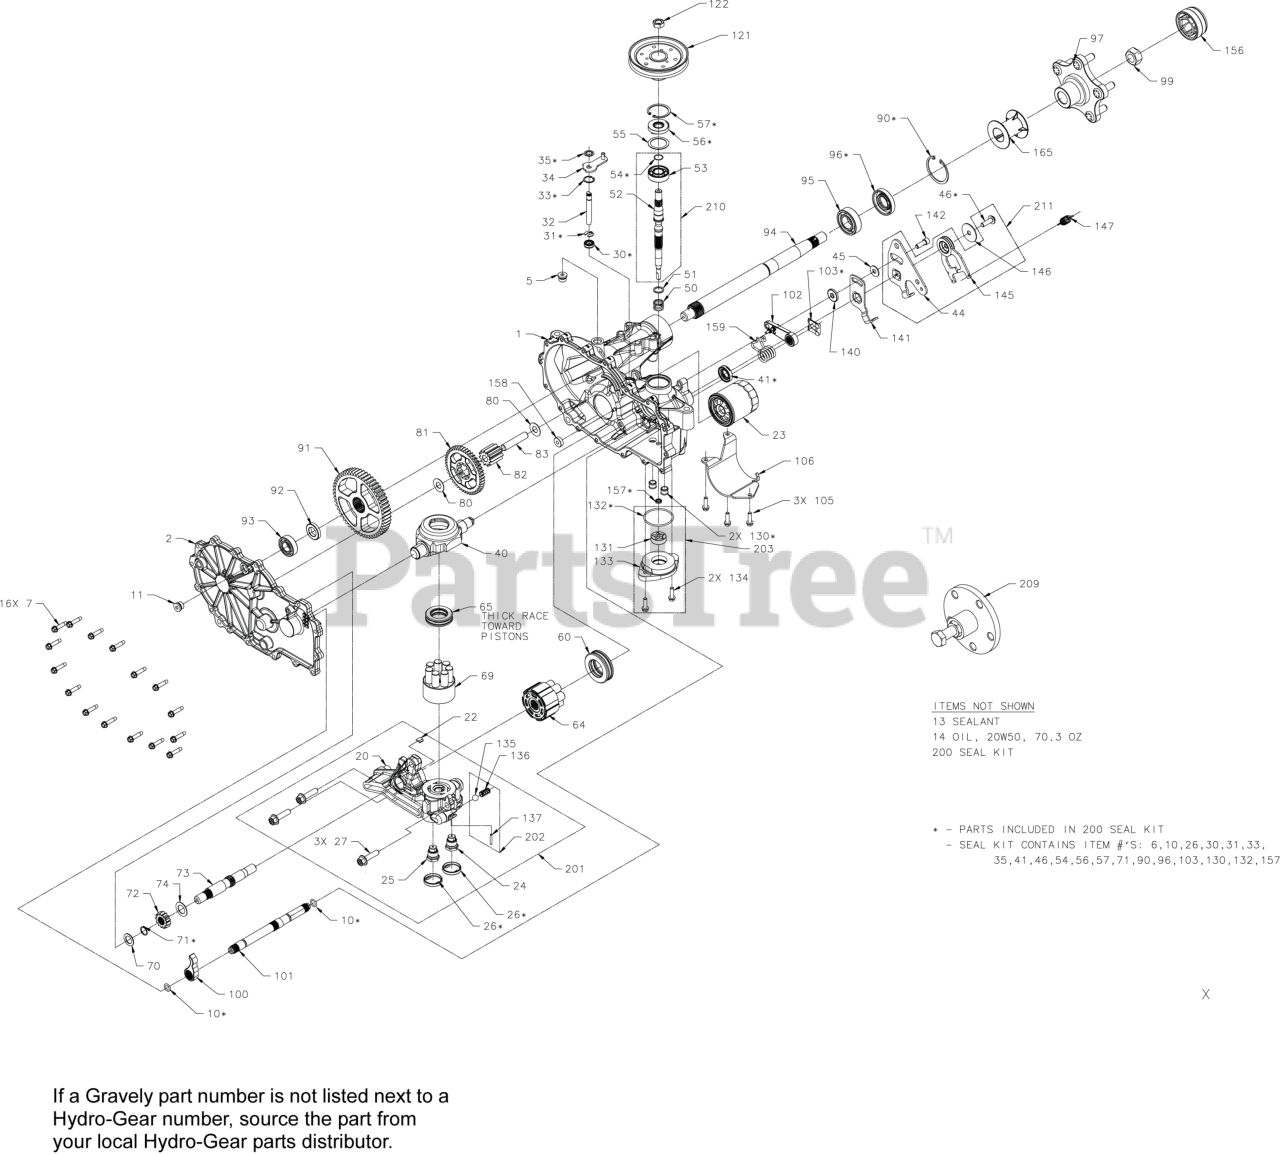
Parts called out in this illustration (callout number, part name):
1	KIT, HOUSING,MAIN,RH,CHRG,CNTL
2	KIT, COVER, SIDE, RH
5	PLUG, 9/16 18 METAL
7	SCREW,HEX WASHER 1/4-20X1.125
11	PLUG, 9/16 18 METAL
13	SEALANT TUBE 10.1OZ.
14	OIL, 20W50
14	FLUID, HYDRO 20W50 QT
22	PLATE, BYPASS
23	FILTER, HYDRO-GEAR 2800 TRANS
26	SEAL, PLUG 1.375 X .250
27	HFHCS 3/8-16X1.5 (PATCH)
30	SEAL, LIP .375X.75X.25
31	RING. RETAINING
32	ROD, BYPASS
33	RING, RET .750
34	ARM, BYPASS
35	RING, RTNG .
40	TRUNNION, SWASHPLATE
46	TWHCS 5/16-24 X 1.00
50	SPRING. BLOCK
51	WASHER. THRUST .59 X .79 X .04
55	WASHER 1.23X1.56X.04
57	RING, RET 1.56 INT
60	HG THRUST BEARING (51462)
64	HG 16CC CYLINDER BLOCK (71579)
65	HG THRUST BLOCK (53502)
69	HG SEVEN PISTON BLOCK (71971)
71	RING, RET 62 EXT
72	GEAR, 13T, STEEL
73	SHAFT, MOTOR
74	WASHER .71 X 1.16 X .04
80	WASHER .5X1.0X.03
82	GEAR 11 TOOTH STEEL
83	JACK SHAFT (PIN)
90	RING, RETAINING
91	GEAR, 54T
94	SHAFT, AXLE
97	HUB, HYDROGEAR P/N 71691
100	PAWL, BRAKE
101	SHAFT, BRAKE
102	KIT, BRAKE ARM
103	CLIP, RETAINING
106	GUARD, FILTER, RH
121	PULLEY, 4.5 INCH
122	NUT,HEX JAM 1/2-20 W/ PATCH
130	TUBE, CONNECTING
131	GEROTOR ASSEMBLY (1.9 cc/rev)
132	O-RING HYDROGEAR 52250
133	COVER, CHARGE PUMP
141	ARM, NEUTRAL RIGHT
142	SHCS 5/16-24X1 PATCH
147	SPRING, HYDROGEAR P/N 51833
157	SEAL, LIP 8 X 12 X 3 VC
158	MAGNET, RING
159	SPRING, TORSION CCW
165	TUBE, AXLE 2.03
200	KIT, SEAL
201	HG CENTER SECTION RH(71972)
202	KIT CHARGE RELIEF
203	KIT, CHARGE PUMP
209	HUB PULLER 5 BLT
210	INPUT SHAFT HG 71978
211	RTN KIT HYDROGEAR P/N 71597
